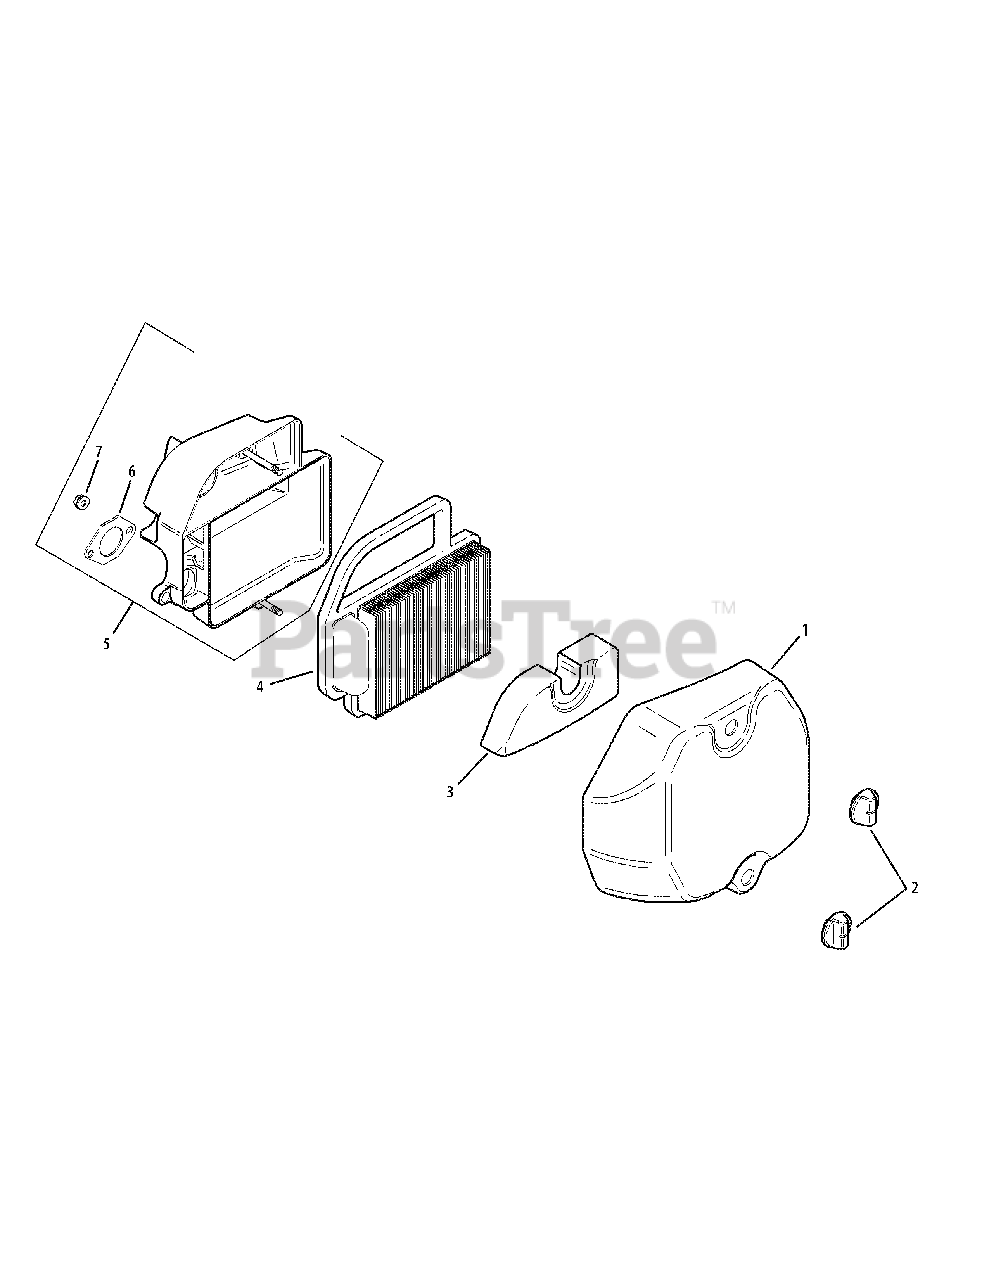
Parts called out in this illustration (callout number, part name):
1	Cover, air cleaner
3	Element, precleaner
4	Element, air cleaner
5	Kit, air cleaner base
6	Gasket, air cleaner base
7	Nut, hex, Flange M6 x 1.0
